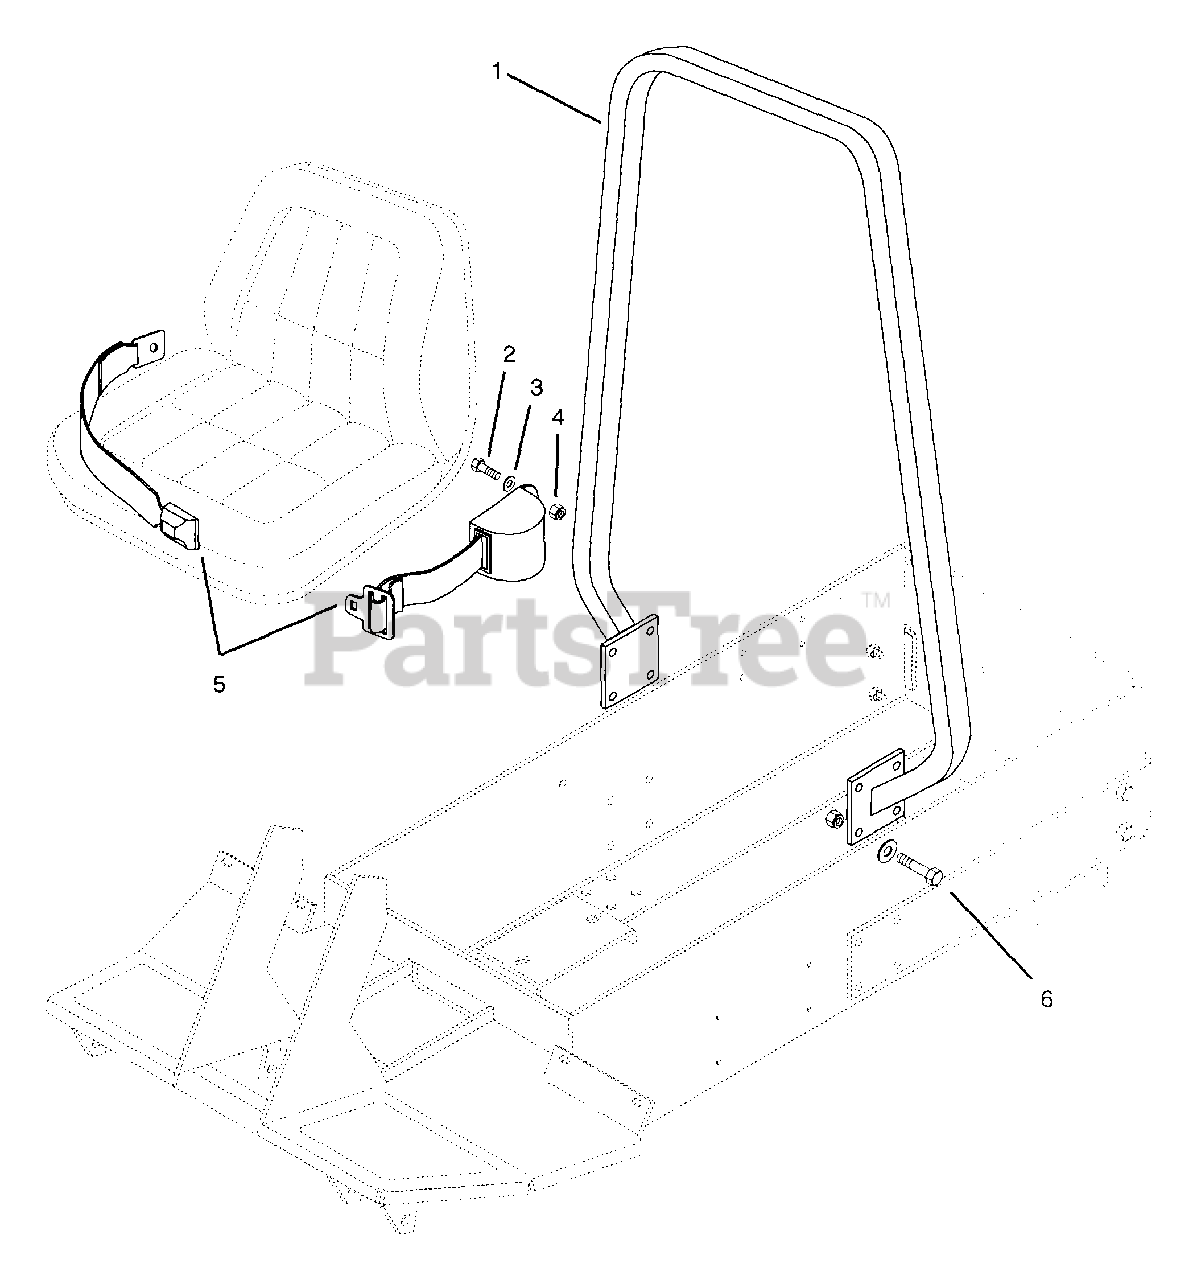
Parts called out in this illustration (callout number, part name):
1	Weldment, Rollover Bar
2	Bolt - Hex .44-14 x 1.0 Grade 5
3	Washer - Flat - Steel .531 x .062 x .095
4	Nut - Locking - Hex .44-14
5	Assembly, Seat Belt
6	Bolt - Hex .50-13 x 1.75 Grade 8
